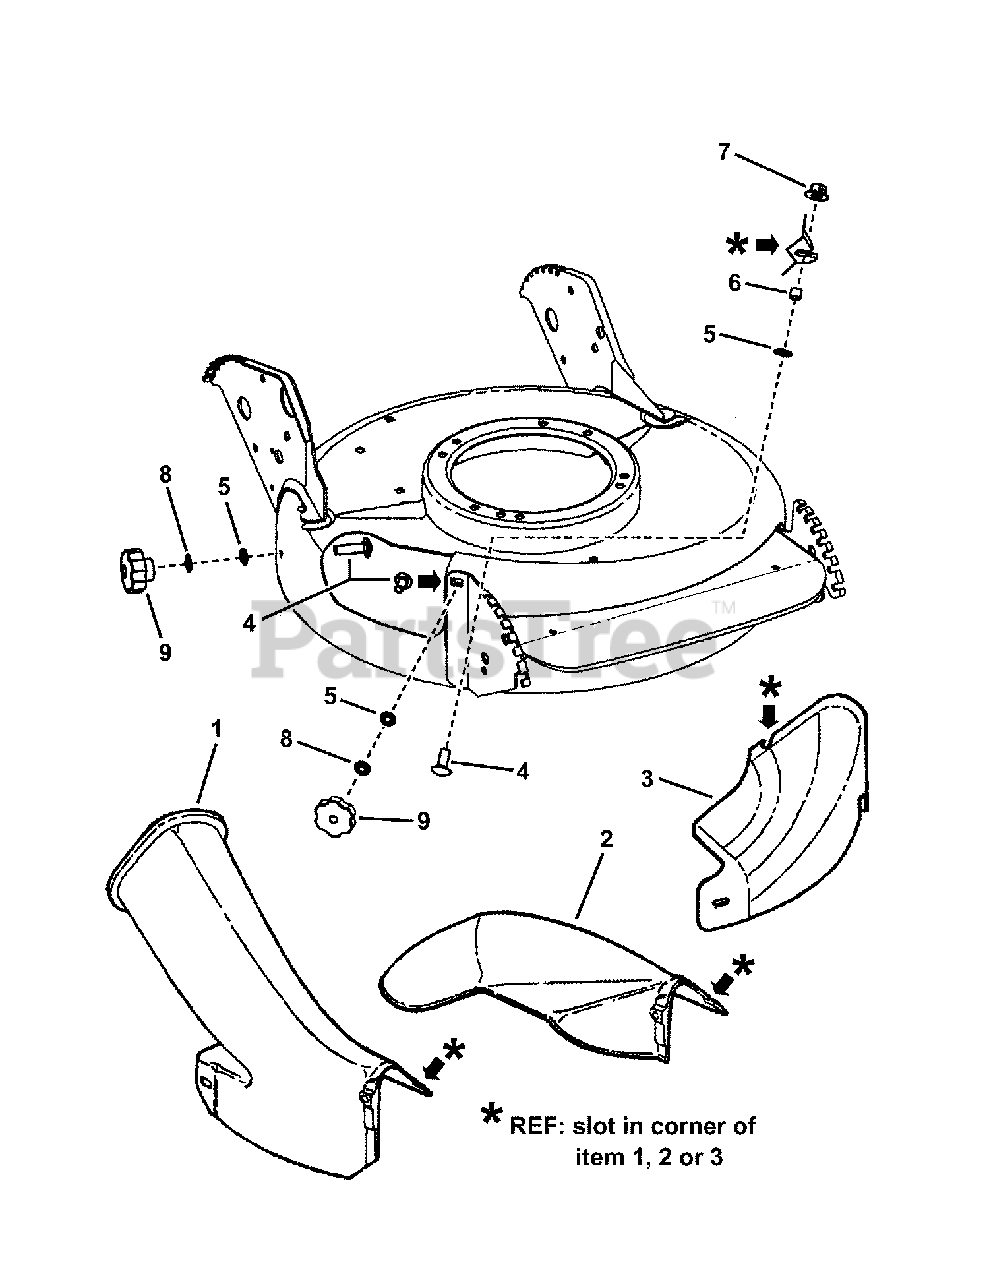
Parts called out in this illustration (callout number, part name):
1	ADAPTER, Grass Bag
2	CHUTE, 21" Side
3	COVER, 21" Deck
4	BOLT, 5/16-18 x 3/4" Short Neck Carriage GR 5
5	RETAINER, 5/16" Bolt
6	SPACER, .316 I.D. x .375 O.D. x .310 thick
7	NUT, 5/16-18 Hex Large Flange Center Lock
8	WASHER, 5/16" Internal/External Tooth Lock
9	KNOB, Fluted, 5/16-18 x .633
